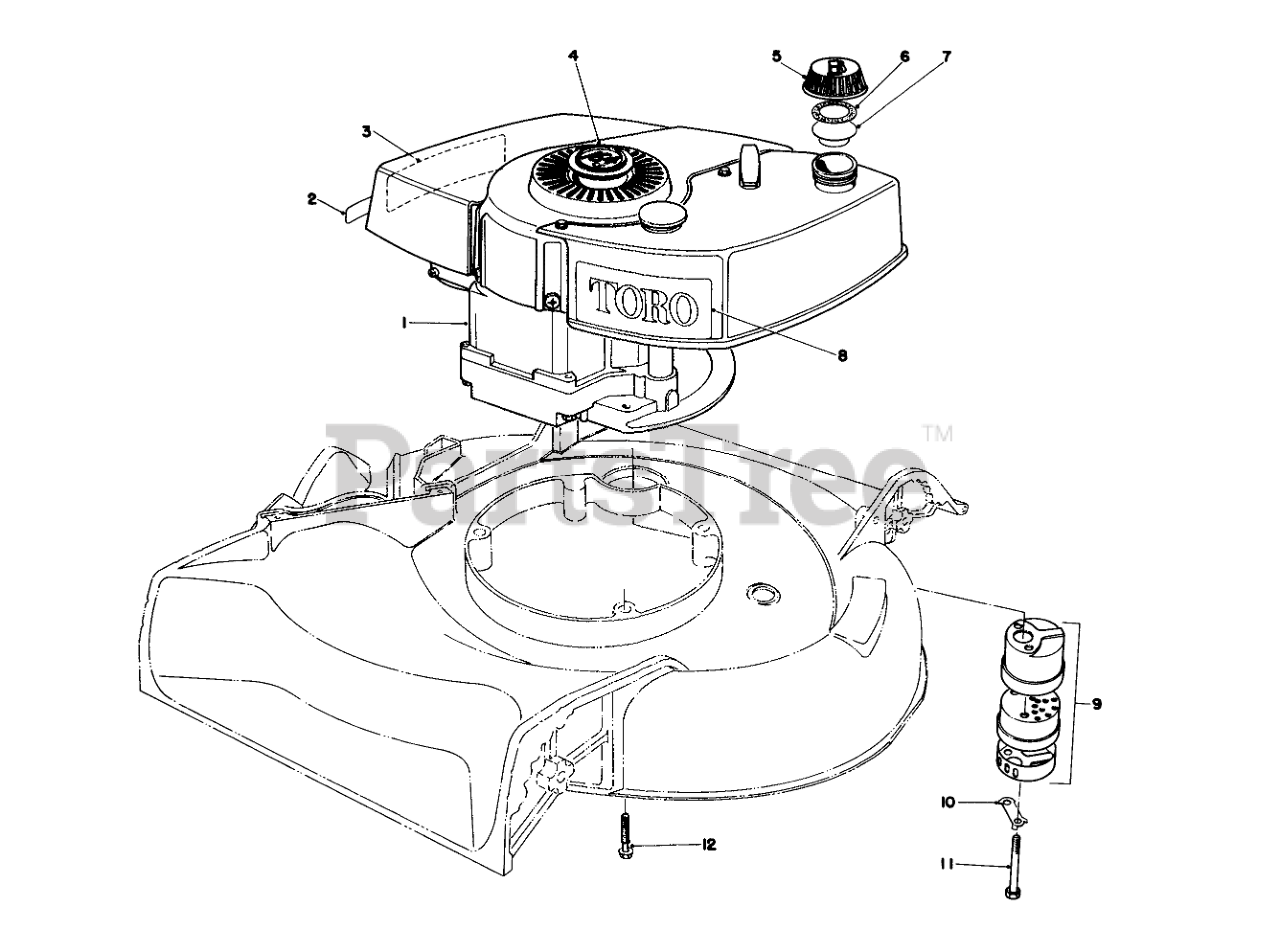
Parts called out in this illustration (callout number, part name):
1	Engine
2	Decal-Primer Bulb
3	Decal Maintenance
4	Plug Button
5	Gas Cap Assembly (Incl. Ref. #6 & 7)
6	GASKET
7	GAS CAP BAFFLE
8	Decal Toro
9	Muffler (Incl. Ref. #10 & 11)
10	CLIP - LOCKING
11	SCREW-HH
12	3/8-16 X 2-3/4 CAPSCR
